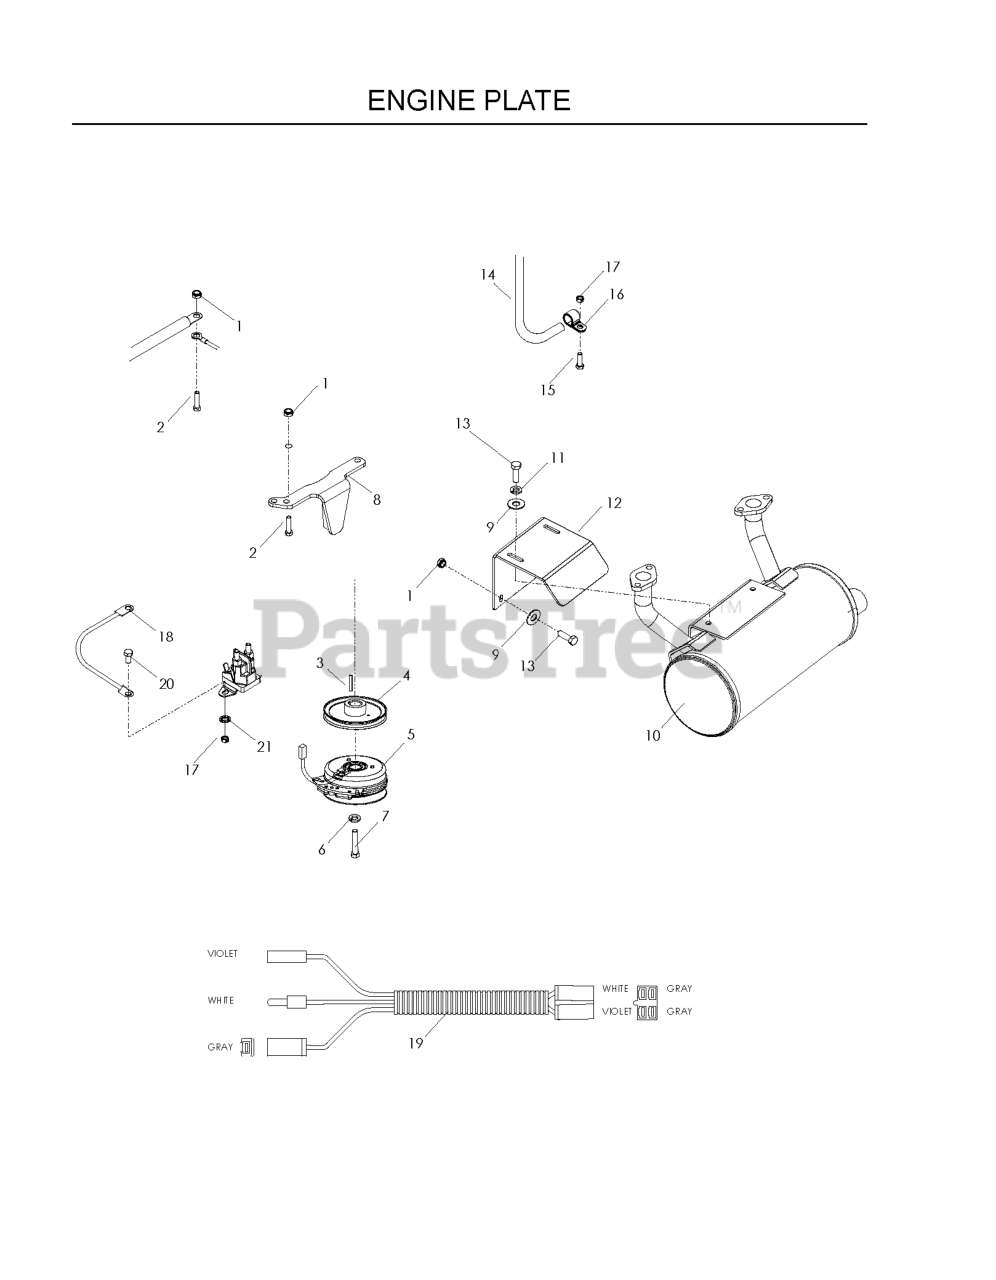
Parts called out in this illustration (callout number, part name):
1	NUT 5/16 NYLOC
2	HCS 5/16C X 1 3/4
3	KEY 1/4" SQ X 1 7/8"
5	ELECTRIC CLUTCH W/CABLE
6	WASHER 7/16 LOCK
7	BOLT 7/16F X 2 1/2
8	WLDT, CLUTCH TIE DOWN BLK
9	WASHER 5/16 FLAT
10	MUFFLER KAWASAKI GEN II
11	WASHER.LOCK.HVY.HLCL.SPR.5/16
12	MUFFLER BRACKET BLACK
13	HCS 5/16C X 1
14	OIL DRAIN HOSE
15	HCS 1/4C X 3/4 HCS
17	NUT 1/4C CENTER LOCK
18	GROUND WIRE (KAW)
19	KAW PIGTAIL
20	HCS 1/4C X 5/8
21	WASHER 1/4 INT TOOTH
